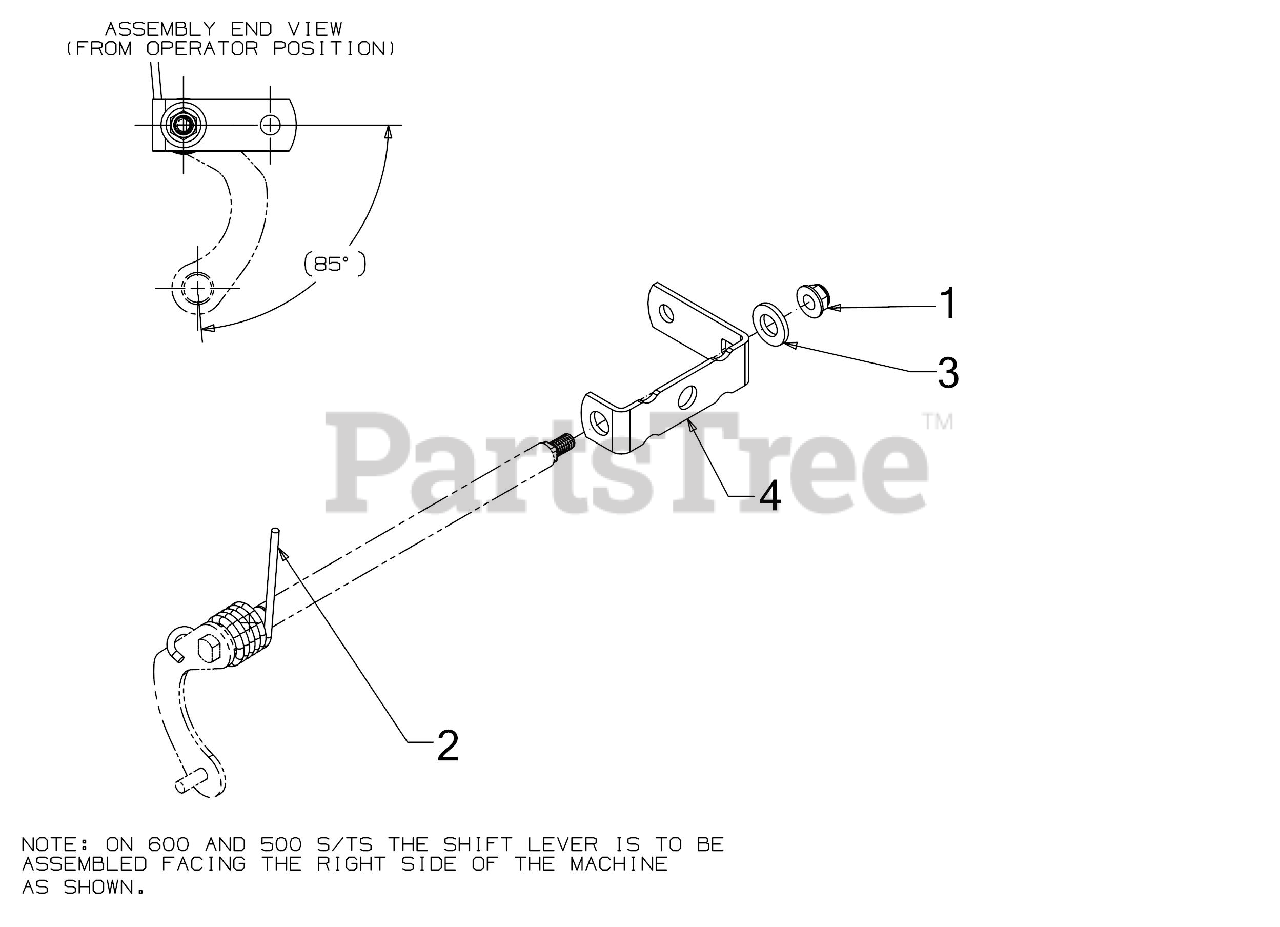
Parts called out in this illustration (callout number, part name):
1	FLANGE LOCK NUT 5/16-18
2	TORSION SPRING
3	FLAT WASHER
4	SPEED SHIFT BRACKET
